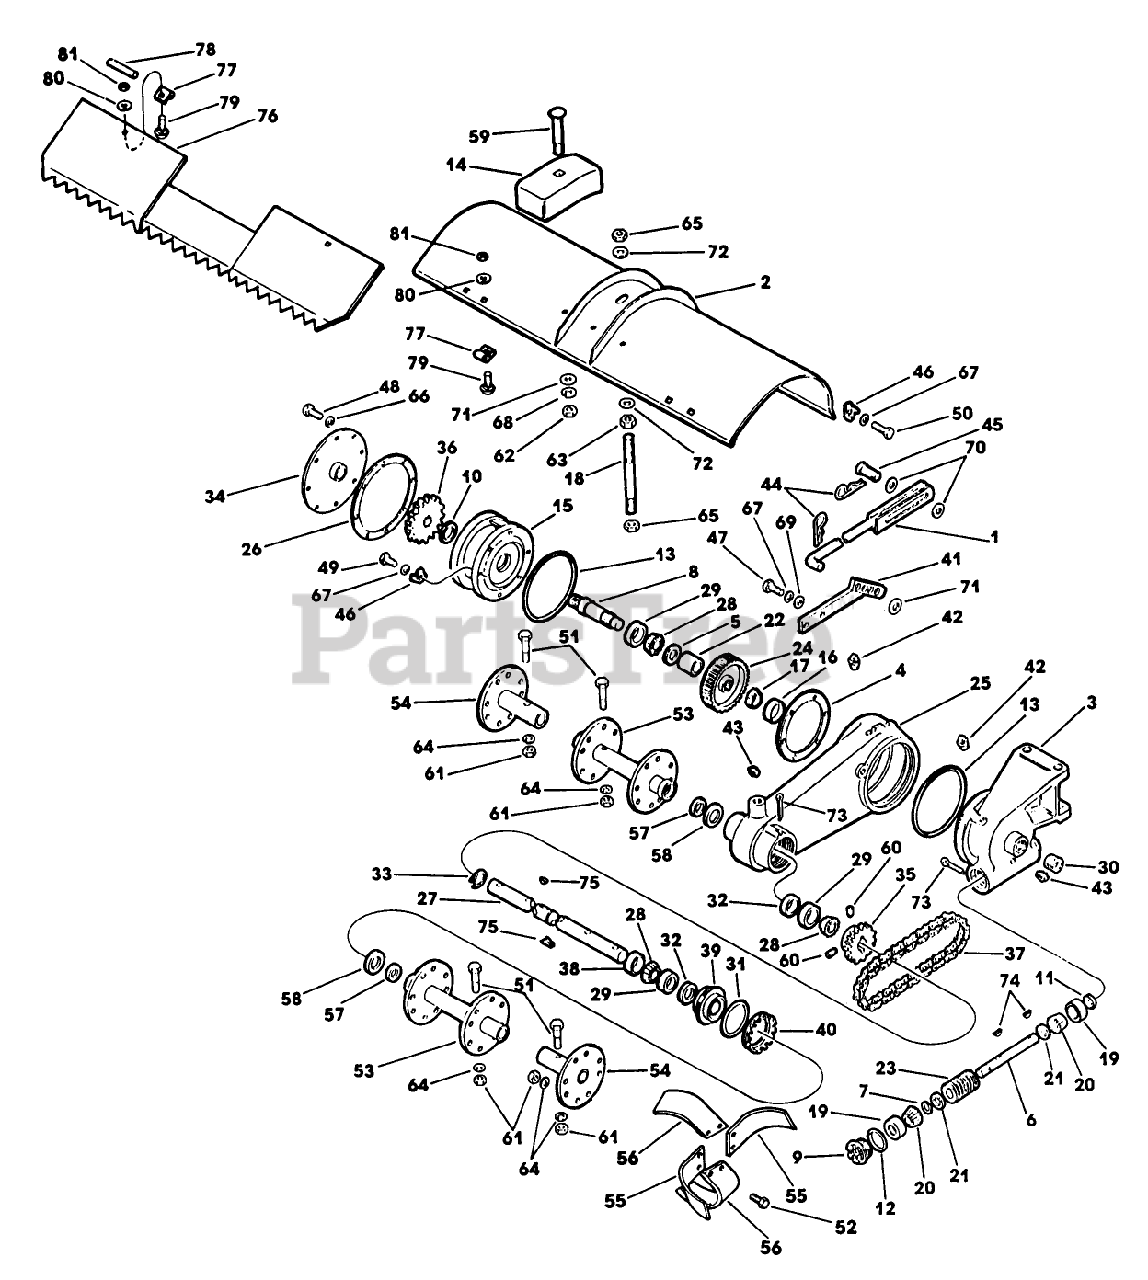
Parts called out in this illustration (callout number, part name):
4	GASKET
5	ROD - LEVEL - RH *F
6	SHAFT WORM
8	SHAFT & SLEEVE AY
10	OIL SEAL - 1.500
15	PLATE
18	STUD-TINE SHIELD
21	SPACER - WORM
22	SPACER-WORM WHEEL
23	WORM
24	WORM WHEEL
26	GASKET
27	SHAFT
37	CHAIN - 60#
38	SPACER
44	PIN - SPRING CLIP
48	SCREW-HH
52	SCREW-CAP HEX HEAD
54	OUTER TINE HUB AY *B
57	FELT SEAL - INNER
58	SEAL - FELT
60	SET SCREW
61	HEX NUT
63	NUT - HEX JAM
67	WASHER
69	WASHER
75	KEY-HYPRO
81	NUT SS
